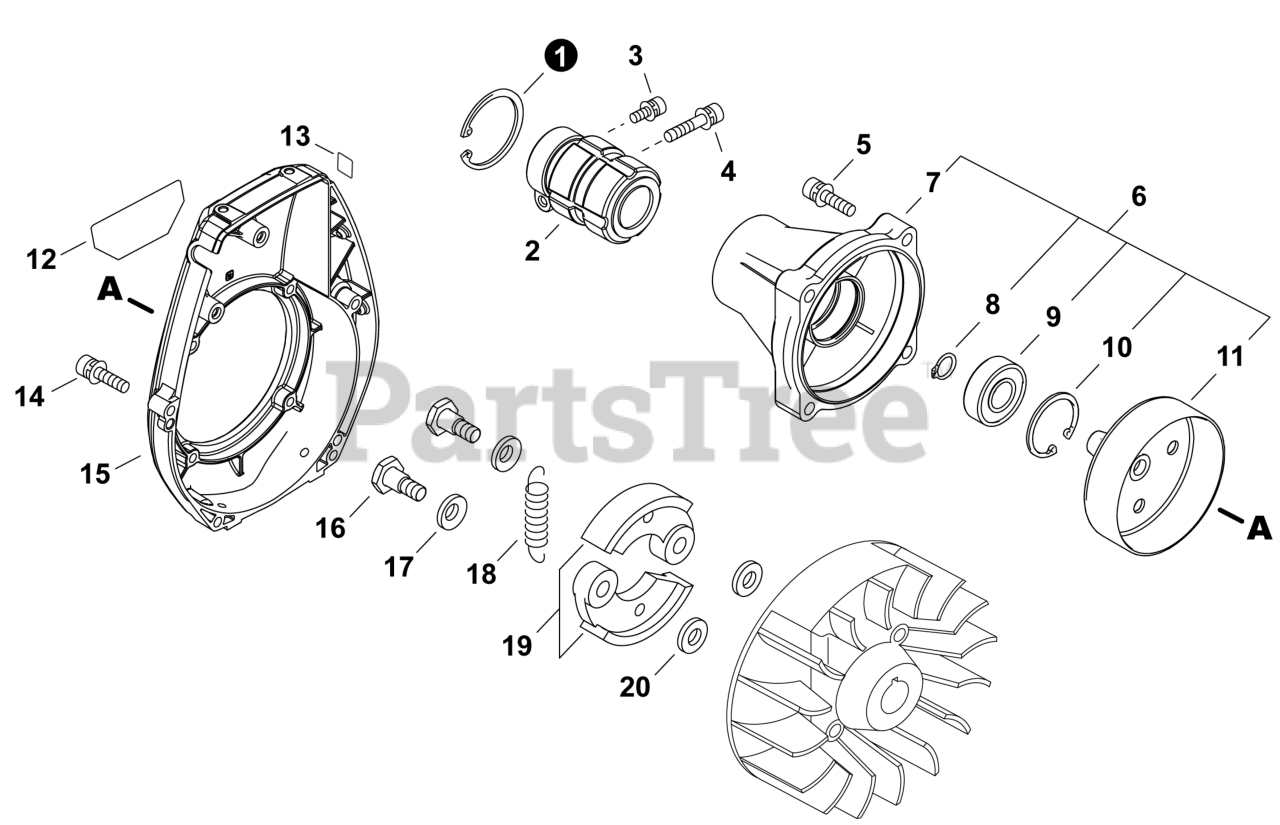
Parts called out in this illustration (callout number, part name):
1	RING, SNAP 45
2	CUSHION, MAIN PIPE
3	BOLT 5x12
4	BOLT 6x30
5	BOLT 6x30
6	CASE ASSY, CLUTCH
7	CASE, CLUTCH
8	RING, SNAP 15
9	BEARING, BALL
10	RING, SNAP 35
11	DRUM, CLUTCH
12	LABEL - MODEL B445
13	LABEL - CAUTION - HOT
14	BOLT 5x25
15	COVER, FAN
17	WASHER, WAVE
18	SPRING, CLUTCH
19	CLUTCH SHOE SET
20	WASHER 8.2x17x1.6
